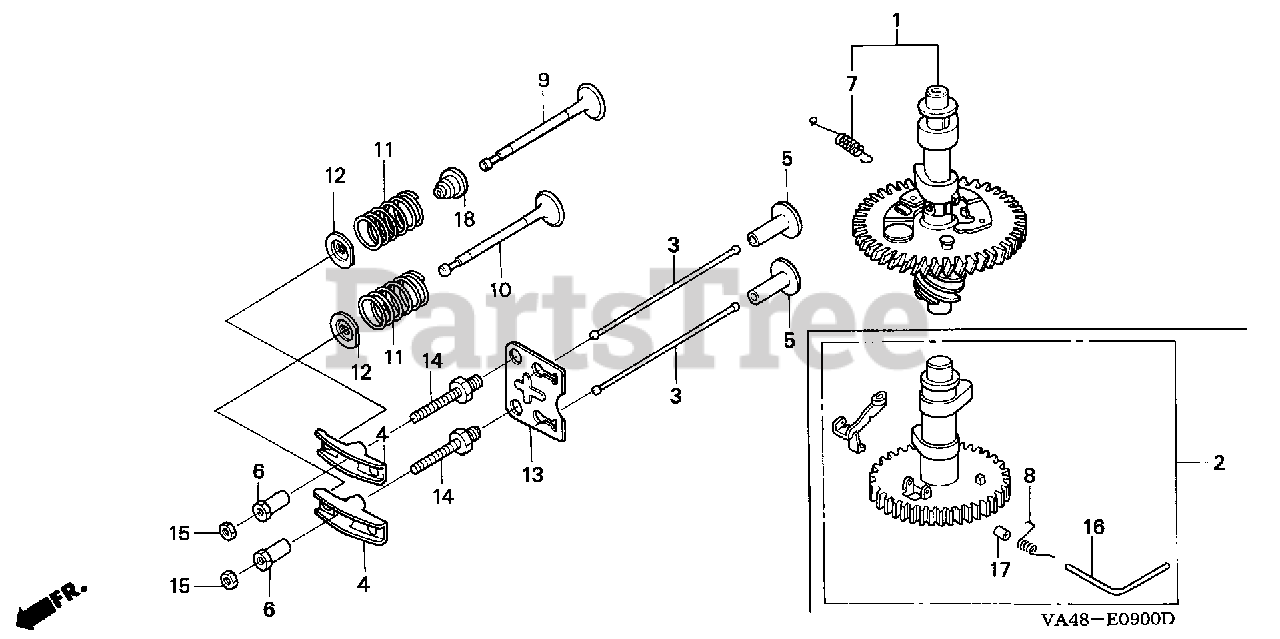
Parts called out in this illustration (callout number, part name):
1	CAMSHAFT ASSY.
3	ROD, PUSH
4	ARM, VALVE ROCKER
5	LIFTER, VALVE
6	PIVOT, ROCKER ARM
7	SPRING, WEIGHT RETURN
9	VALVE, IN.
10	VALVE, EX.
11	SPRING, VALVE
12	RETAINER, IN. VALVE SPRING
13	PLATE, PUSH ROD GUIDE
14	BOLT, PIVOT (8MM)
15	NUT, PIVOT ADJ.
